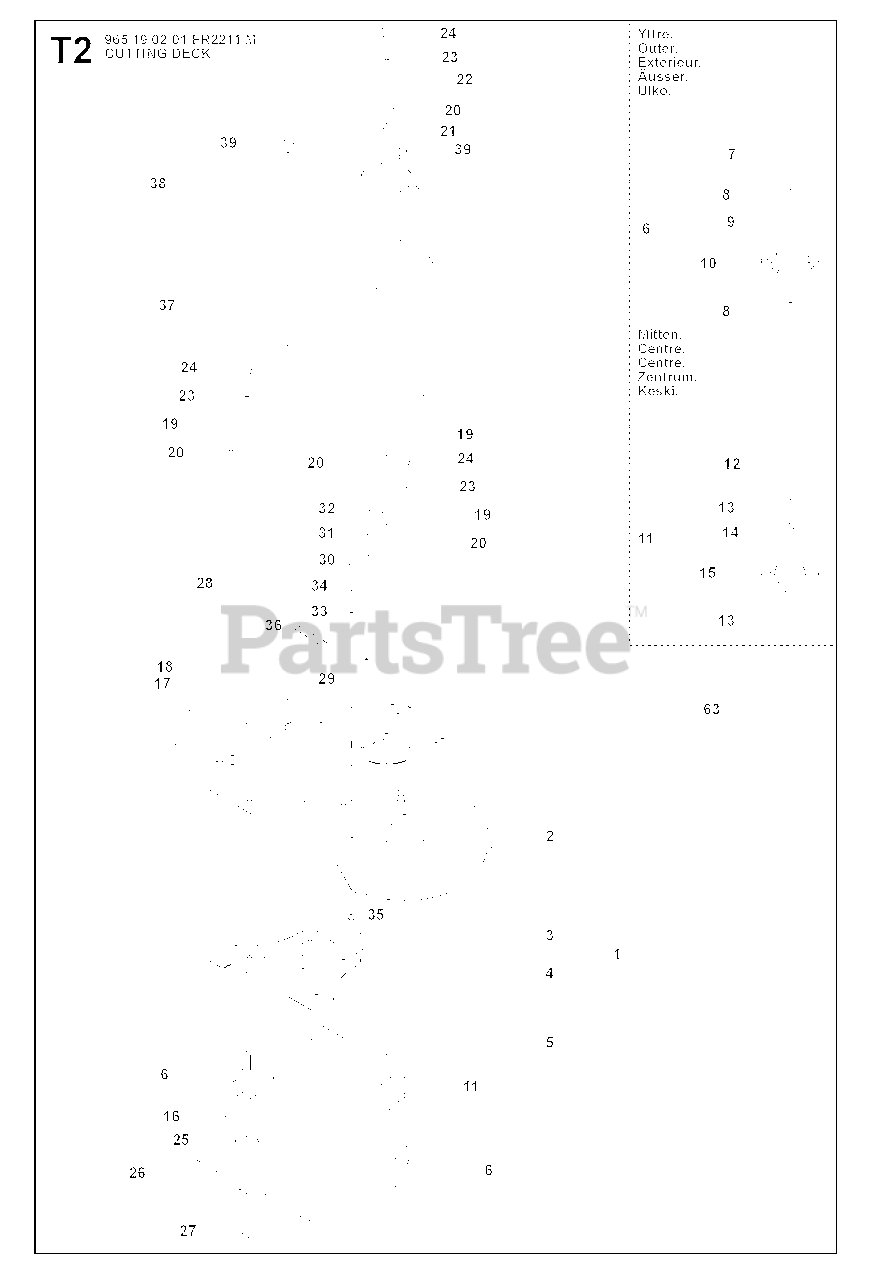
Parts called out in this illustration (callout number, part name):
6	RP SPINDLE ASSY
10	BEARING HOUSING
15	BEARING HOUSING
17	WASHER BRB 8.4X17
18	LOCKNUT M8
30	PULLEY
33	WASHER
35	LOCKNUT M8
